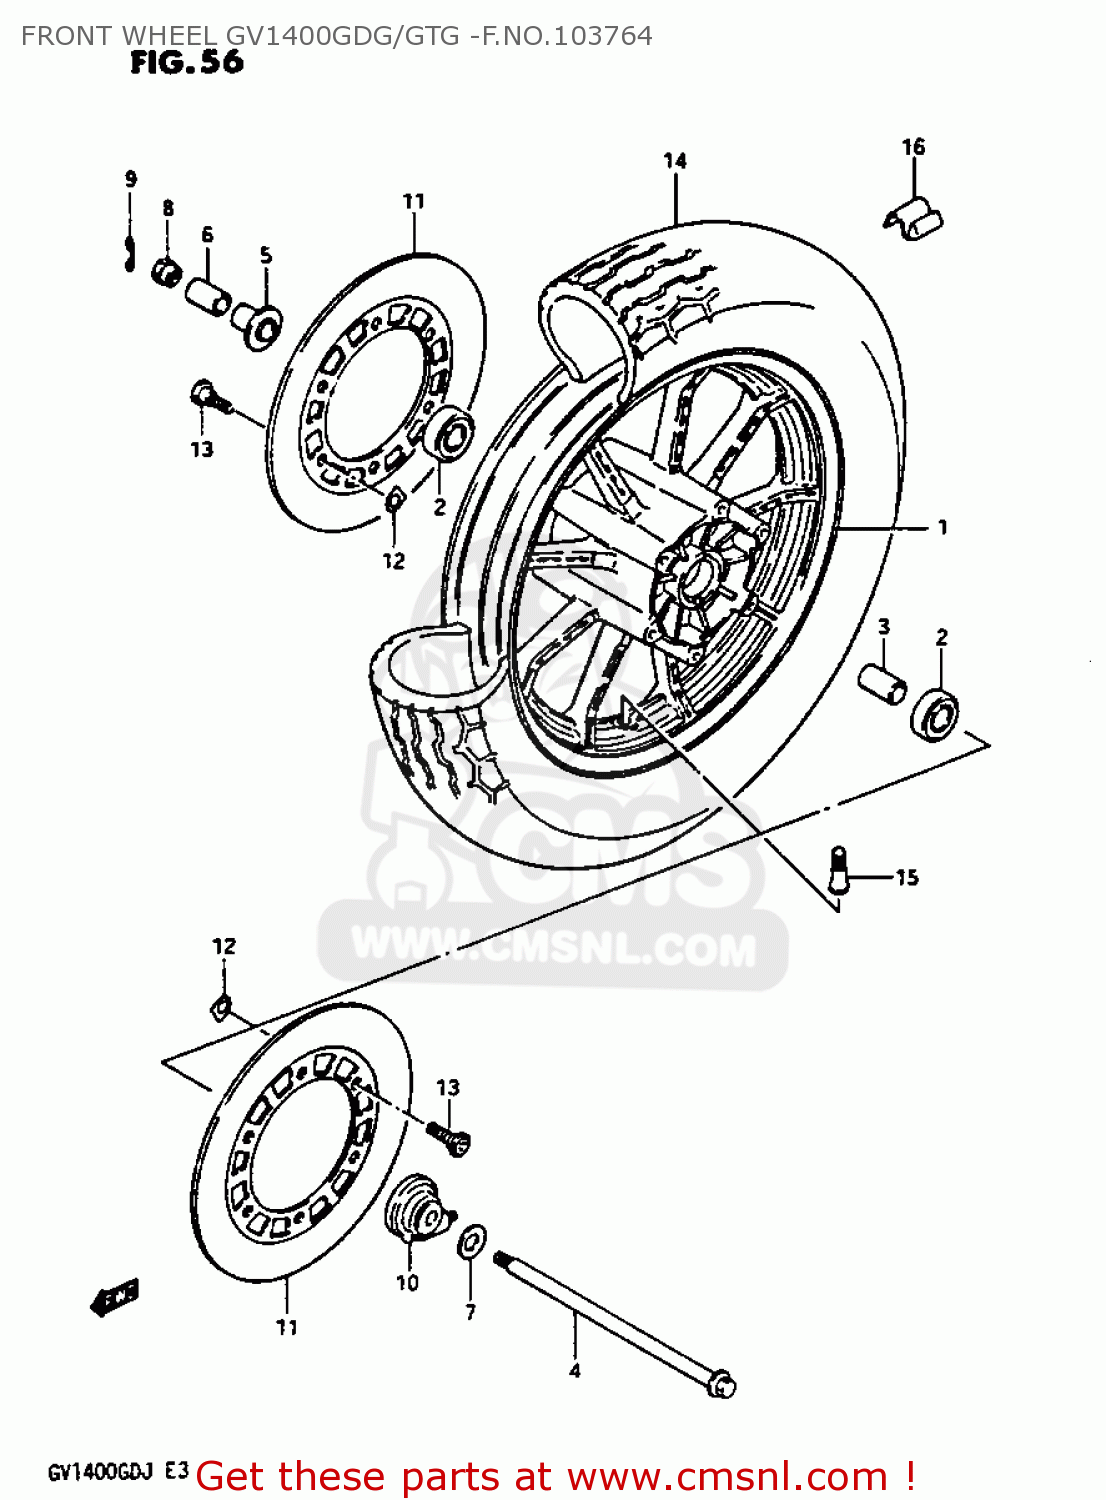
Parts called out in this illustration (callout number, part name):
1	WHEEL,FRONT
2	BEARING
3	SPACER
4	AXLE,FRONT
5	SPACER,FR HUB BEARING,R
6	SPACER,FR AXLE,R
7	WASHER
8	NUT (12MM)
9	PIN,FRONT AXLE
10	BOX ASSY,SPEEDOMETER GEAR
11	DISC,FRONT BRAKE
12	SHIM,BRAKE DISC
13	BOLT(8X25.5)
14	TIRE,FRONT 130/90-16.6
15	VALVE,TIRE TR413 BS
16	BALANCER,WHEEL
